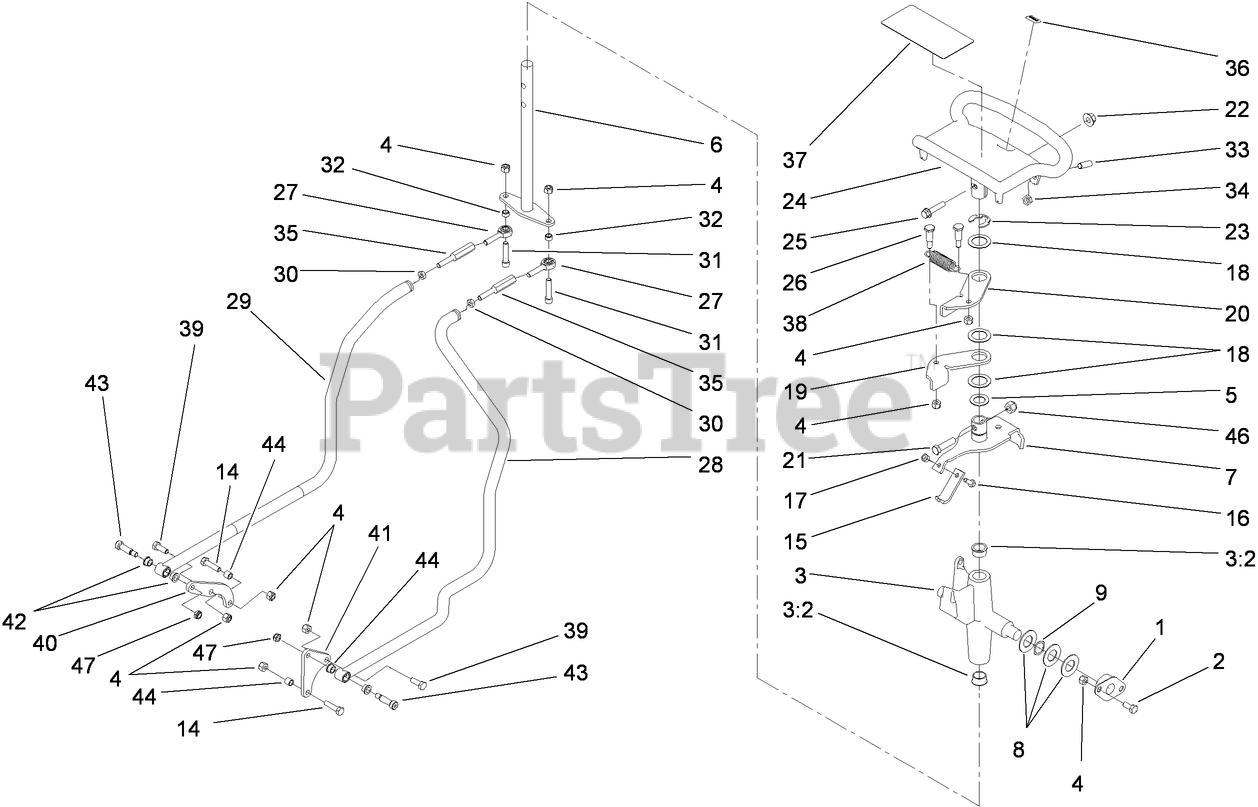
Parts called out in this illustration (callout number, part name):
1	BUSHING
2	SCREW-HH
3	CONTROL SUPPORT ASM
3:2	BEARING-FLANGE
4	NUT-LOCK, NI
5	WASHER-THRUST
6	DRIVE ROD ASM
7	LEVER-PIVOT
8	WASHER-FLAT
9	WASHER-SPRING, WAVE
14	SCREW-HH
15	PLATE-NEUTRAL
16	SCREW-HH
17	NUT-LOCK, NI
18	WASHER-PLAIN
19	LEVER-RETURN, RH
20	LEVER-RETURN, LH
21	SCREW-HH
22	NUT-FLANGE
23	RING-RETAINING
24	HANDLE-CONTROL
25	SCREW-HHF
26	SCREW-SHOULDER
27	BEARING-ROD END, LH
28	ROD-CONTROL, LH
29	ROD-CONTROL, RH
30	NUT-JAM
31	SCREW-HSH
32	SPACER-LEVER, TRACTION
33	SCREW-SET
34	NUT-JAM
35	LINK-CONTROL
36	DECAL
37	DECAL-TRACTION
38	SPRING-EXTENSION
39	SCREW-HH
40	PLATE-ADAPTER, CONTROL, RH
41	PLATE-ADAPTER, CONTROL, LH
42	BUSHING-FLANGED
43	BOLT-SHOULDER
44	SPACER
46	NUT-LOCK, NI
47	NUT-LOCK, NI
